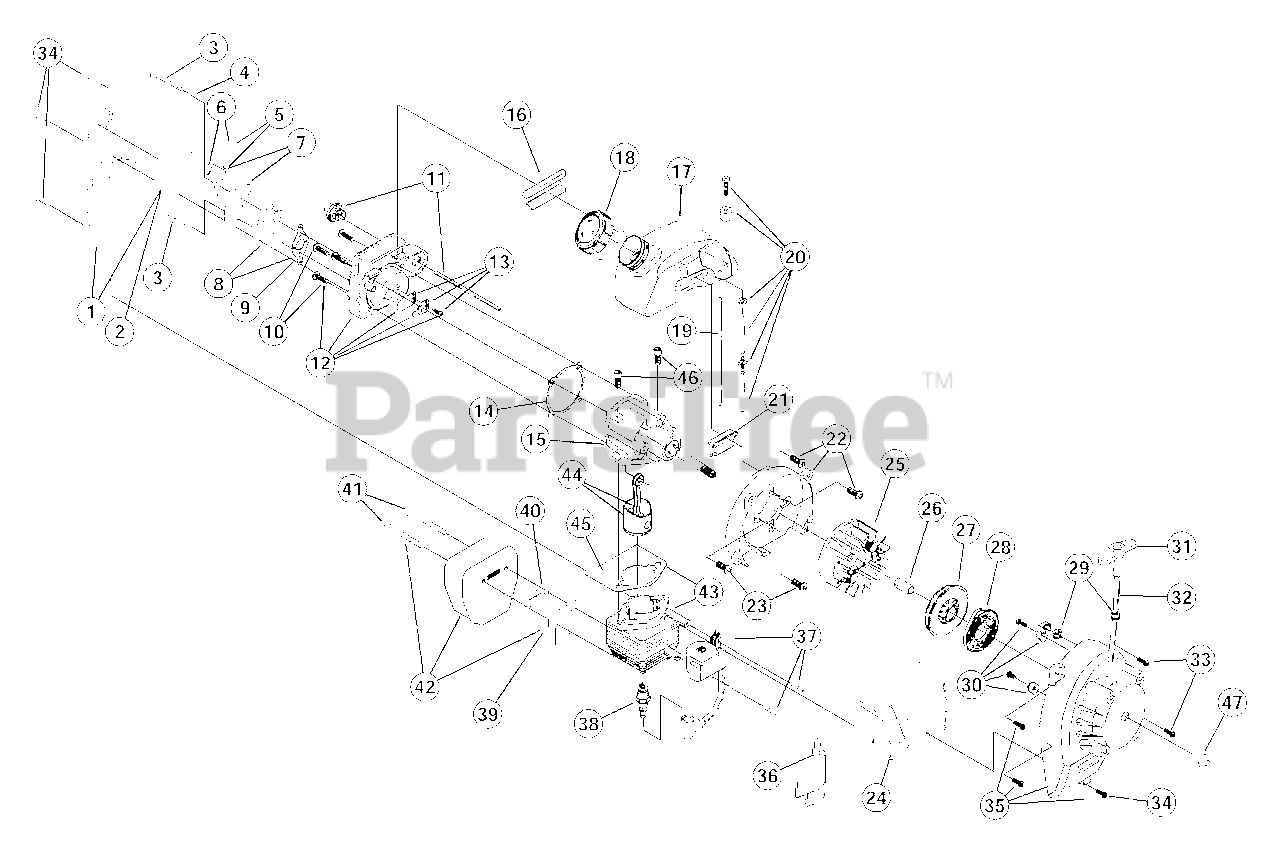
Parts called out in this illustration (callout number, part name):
1	Air Cleaner/Muffler Cover Assembly
2	Air Cleaner Filter
3	Carburetor Mounting Screw
4	Wavey Washer
5	Choke Lever Assembly
6	Choke Knob and Screw
7	Choke Lever and Plate
8	Carburetor Assembly
9	Carburetor Gasket
10	Carb Mount Screw
11	Primer and Hose Assembly
12	Carb Mount Assembly
13	Reed Assembly
14	Carburetor Mount Gasket
15	Crank Case Service Assembly
16	Rear Mounting Pad
17	Fuel Tank Assembly
18	Fuel Cap Assembly
19	Fuel Return Line
20	Fuel Line Assembly
21	Front Mounting Pad
22	Shroud Assembly
23	Shroud Screw
24	Shroud Extension
25	Flywheel Assembly
27	Recoil Pulley Assembly
28	Recoil Spring
29	Rope Guide
30	Pulley Retainer Assembly
31	Pull Handle
33	Housing Screw
34	Cover Screw
35	Starter Housing Assembly
36	Wire Lead Assembly
37	Module Assembly
38	Spark Plug
39	Exhaust Gasket
40	Spark Arrestor Screen
41	Muffler Mounting Bolt Assembly
42	Muffler Assembly
43	Cylinder Assembly
44	Piston and Rod Assembly
45	Cylinder Gasket
46	Cylinder Bolt
47	Crankshaft Extension
